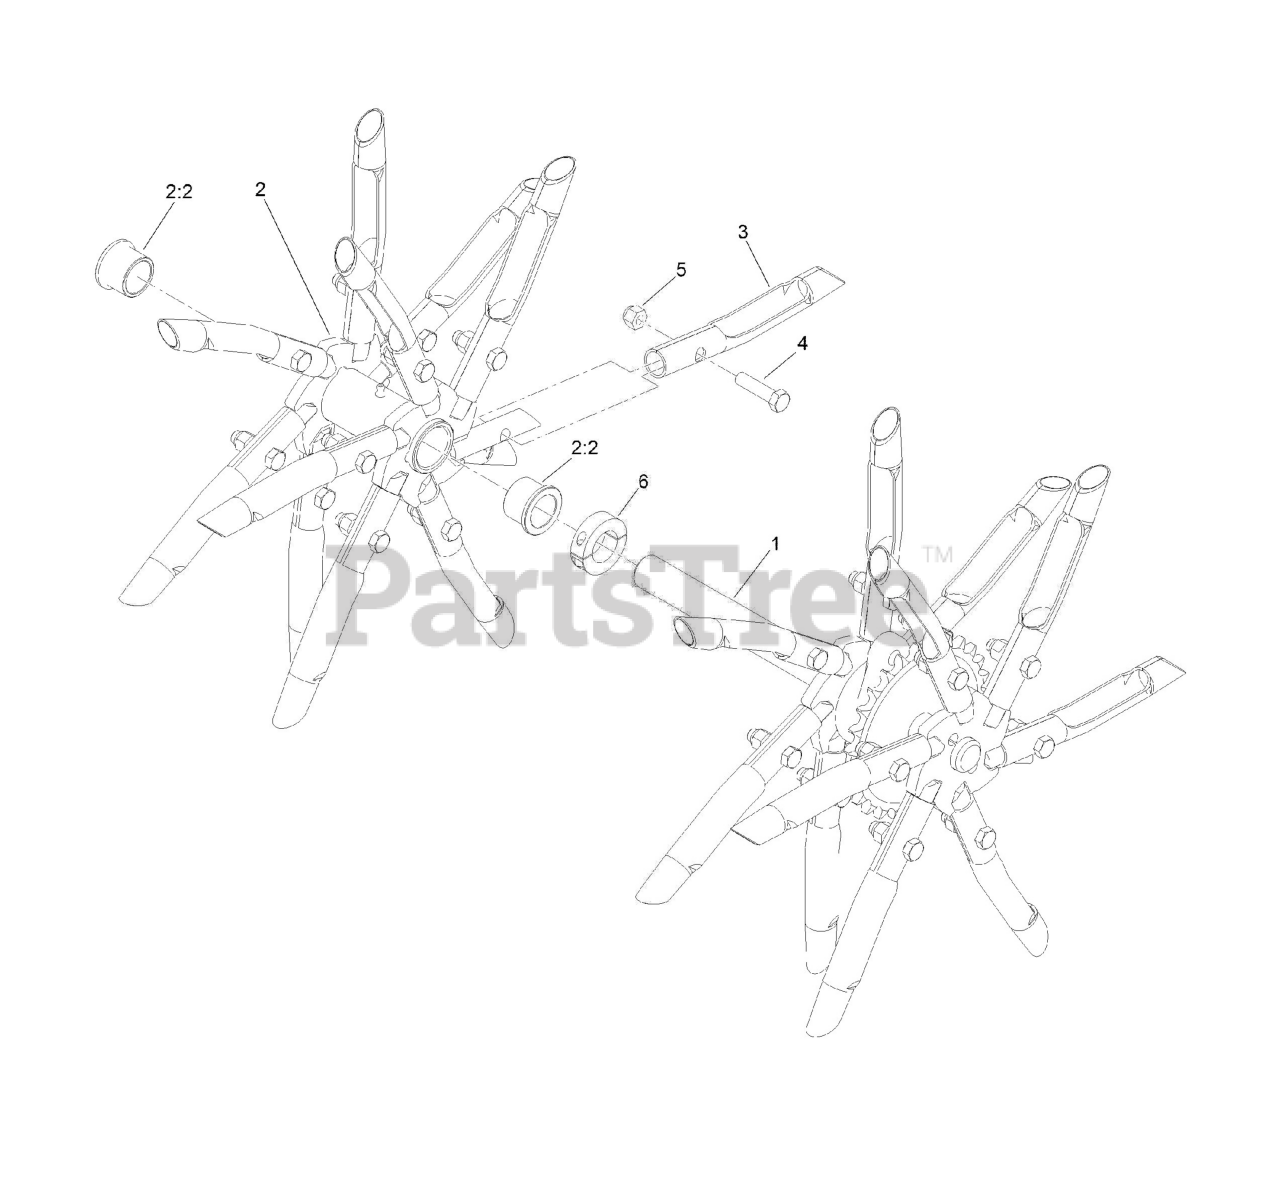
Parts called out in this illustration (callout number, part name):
1	TINE SHAFT- LH
2	ASM-FLOAT TINE SHAFT
2:2	BUSHING-FLANGE
3	TINE-CORING (3/4 INCH)
4	SCREW-HH
5	NUT-LOCK, NI
6	COLLAR-LOCKING
